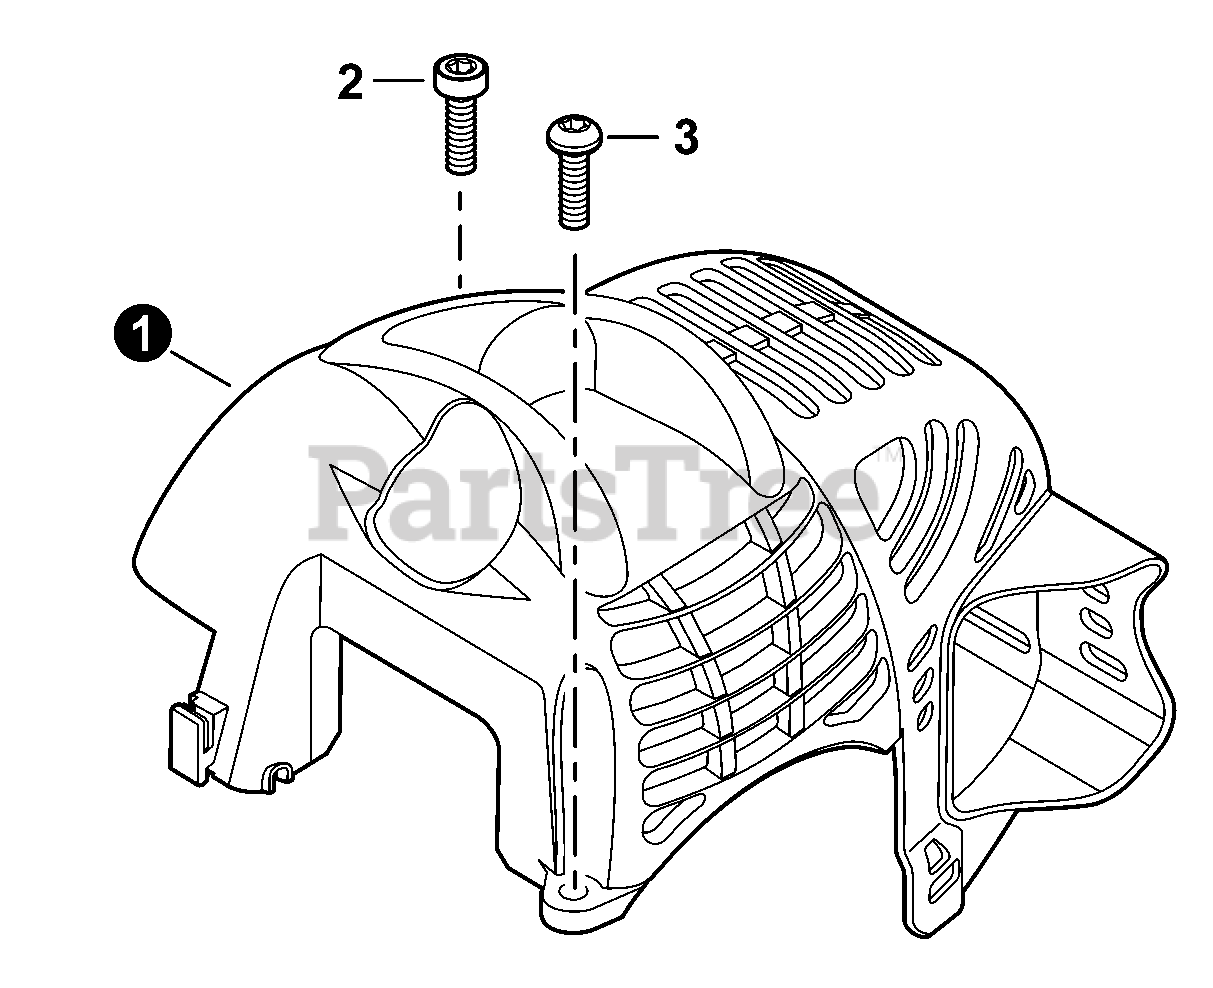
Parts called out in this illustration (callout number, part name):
1	COVER, ENGINE
2	BOLT, TORX 5×16
3	BOLT, TORX 5×16
